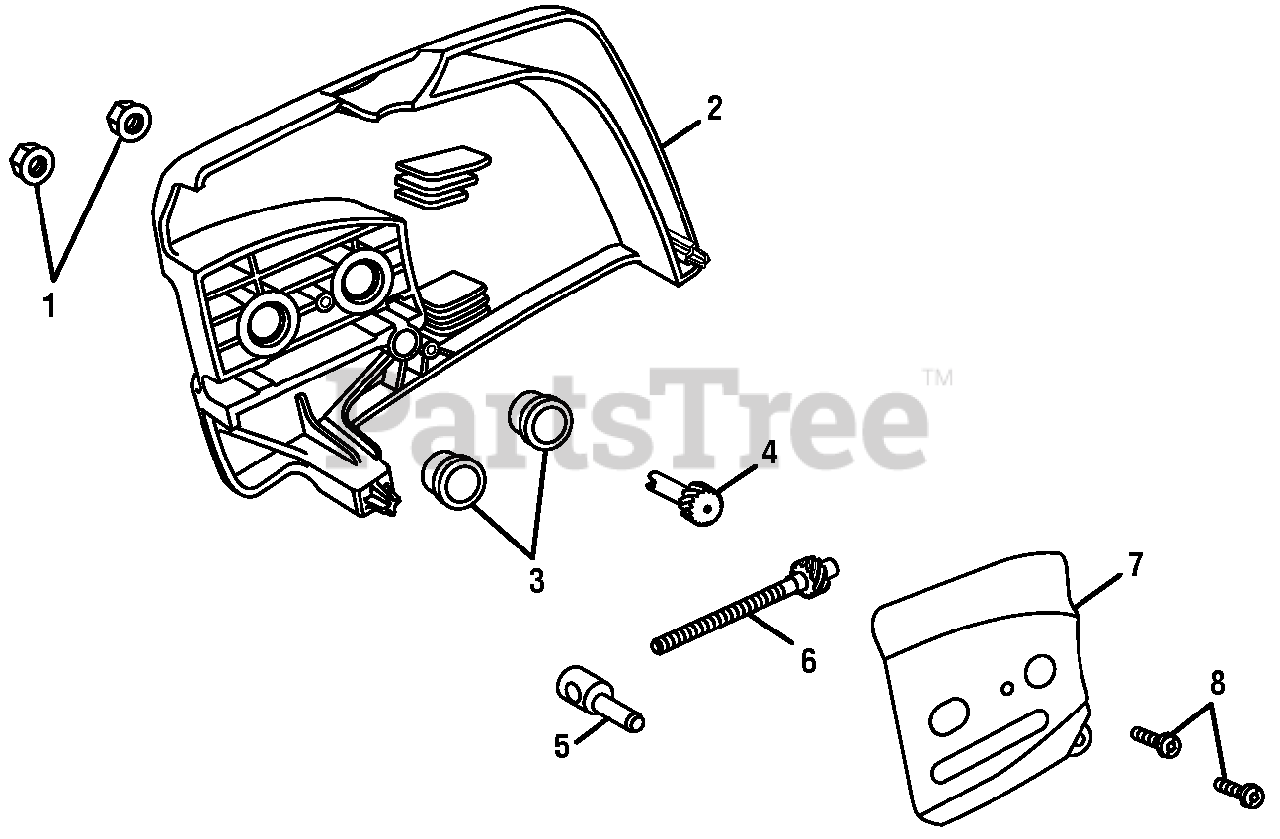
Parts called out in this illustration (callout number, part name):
1	Nut (5/16-18, Hex Hd.)
2	Clutch Cover
3	Clutch Cover Insert
4	Adjusting Gear
5	Adjusting Nut
6	Adjusting Screw
7	Guide Plate
8	Screw (M4, Torx T20)
